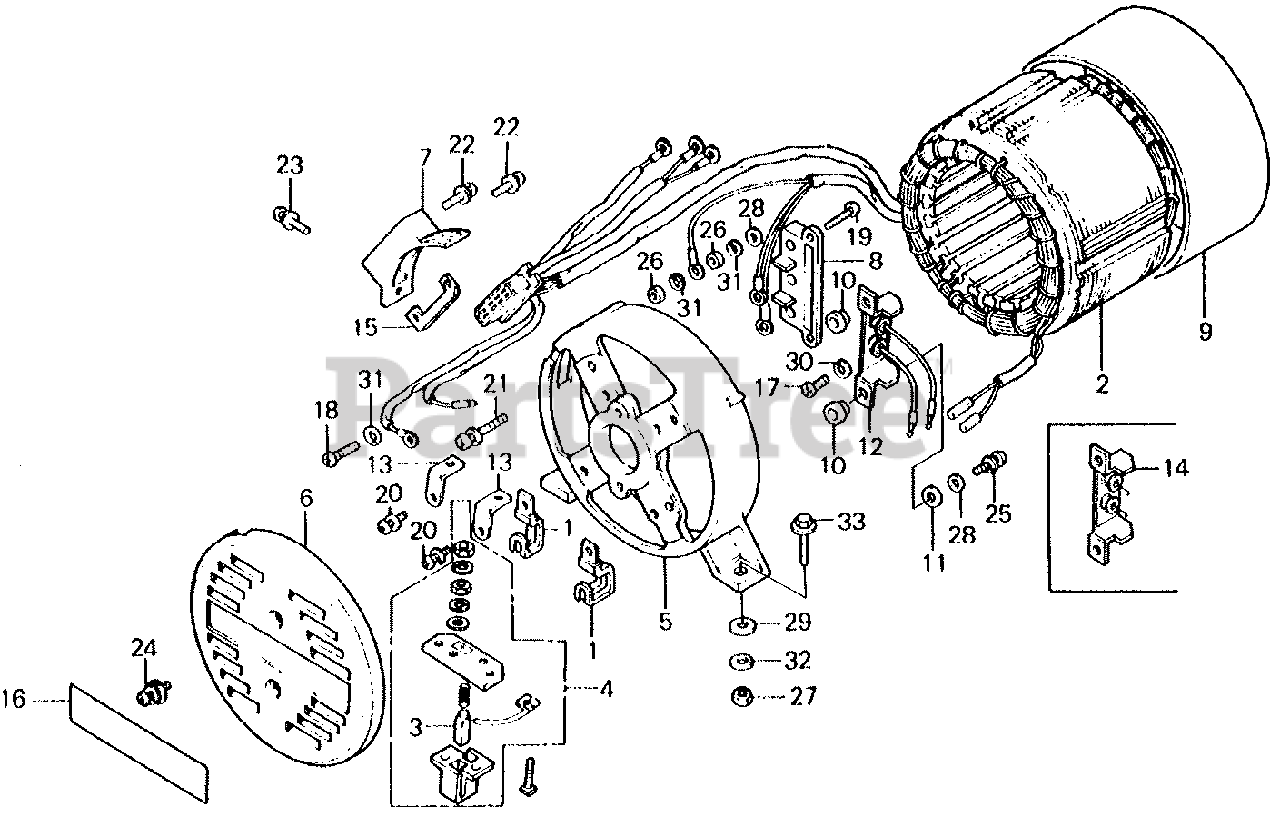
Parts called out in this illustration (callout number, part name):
1	CLAMP B, WIRE
2	STATOR ASSY.
3	HOLDER, BRUSH
4	HOLDER, BRUSH
5	HOUSING, RR. *NH31* (MCKINLEY WHITE)
6	COVER, GENERATOR END *R8* (BRIGHT RED)
7	COVER, RECEPTACLE
8	TERMINAL, VOLT CHANGE
9	COVER, STATOR *NH31* (MCKINLEY WHITE)
10	BUSH, INSULATING
11	WASHER, INSULATING
12	DIODE ASSY., D.C. (NOT AVAILABLE)
13	STAY, BRUSH HOLDER
14	DIODE, D.C.
15	PLATE, CONNECTOR SETTING
16	PLATE, CAUTION
17	SCREW, PAN (4X8)
18	SCREW, PAN (5X10)
19	SCREW, PAN (5X20)
20	SCREW-WASHER (5X10)
21	SCREW-WASHER (5X25)
22	SCREW-WASHER (3X10)
23	SCREW-WASHER (4X12)
24	SCREW-WASHER (5X10)
25	SCREW-WASHER (5X16)
26	NUT, HEX. (5MM)
27	NUT, HEX. (8MM)
28	WASHER, PLAIN (5MM)
29	WASHER, PLAIN (8MM)
30	WASHER, SPRING (4MM)
31	WASHER, SPRING (5MM)
32	WASHER, SPRING (8MM)
33	BOLT, FLANGE (8X28)
